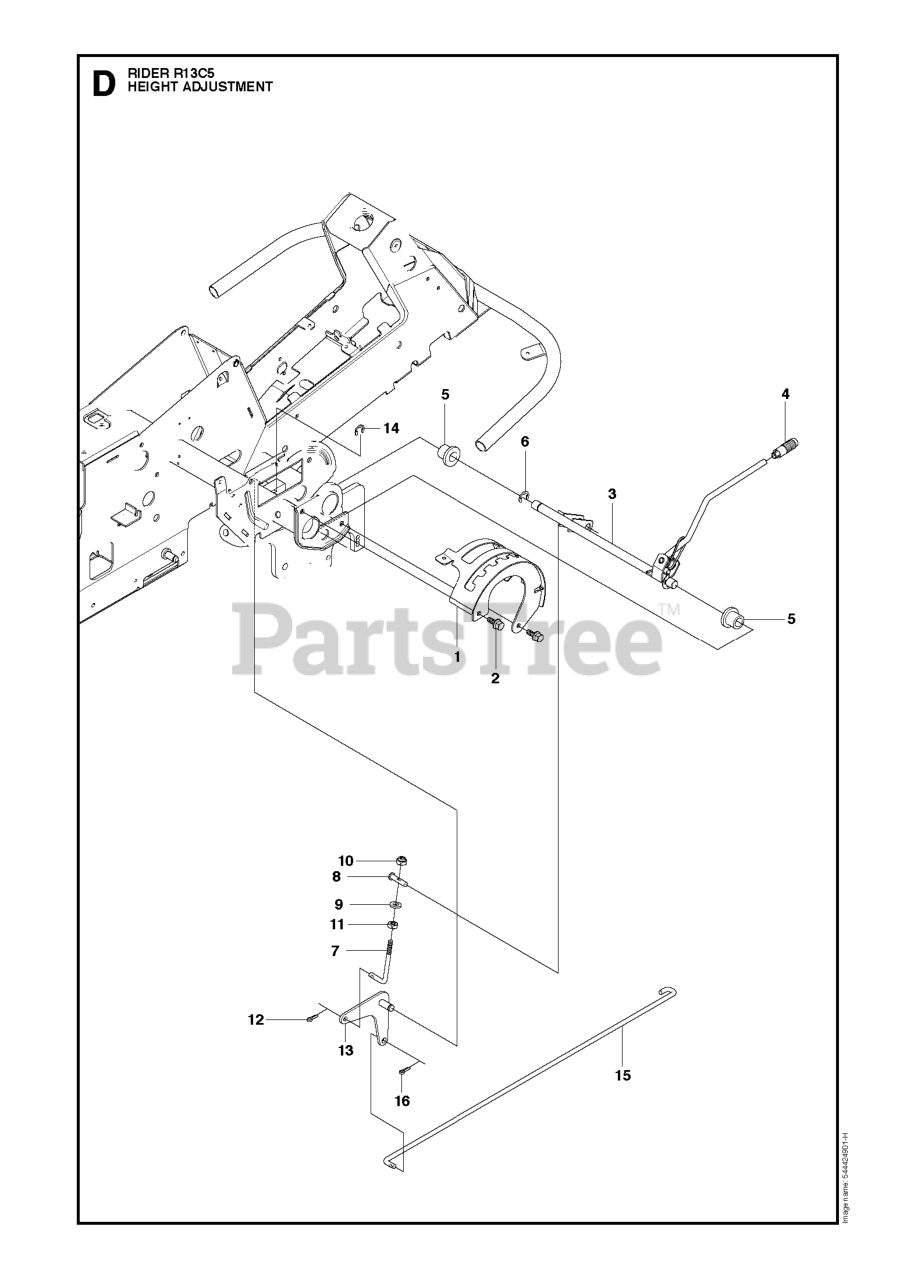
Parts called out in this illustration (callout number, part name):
1	CONTROL PLATE
3	HEIGHT ADJUSTER
4	GEAR STICK KNOB
5	BUSHING
9	WASHER
10	LOCKNUT M8
11	NUT
13	LINK HEIGHT ADJUSTMENT
14	RETAINING RING
15	CONNECTION ROD
